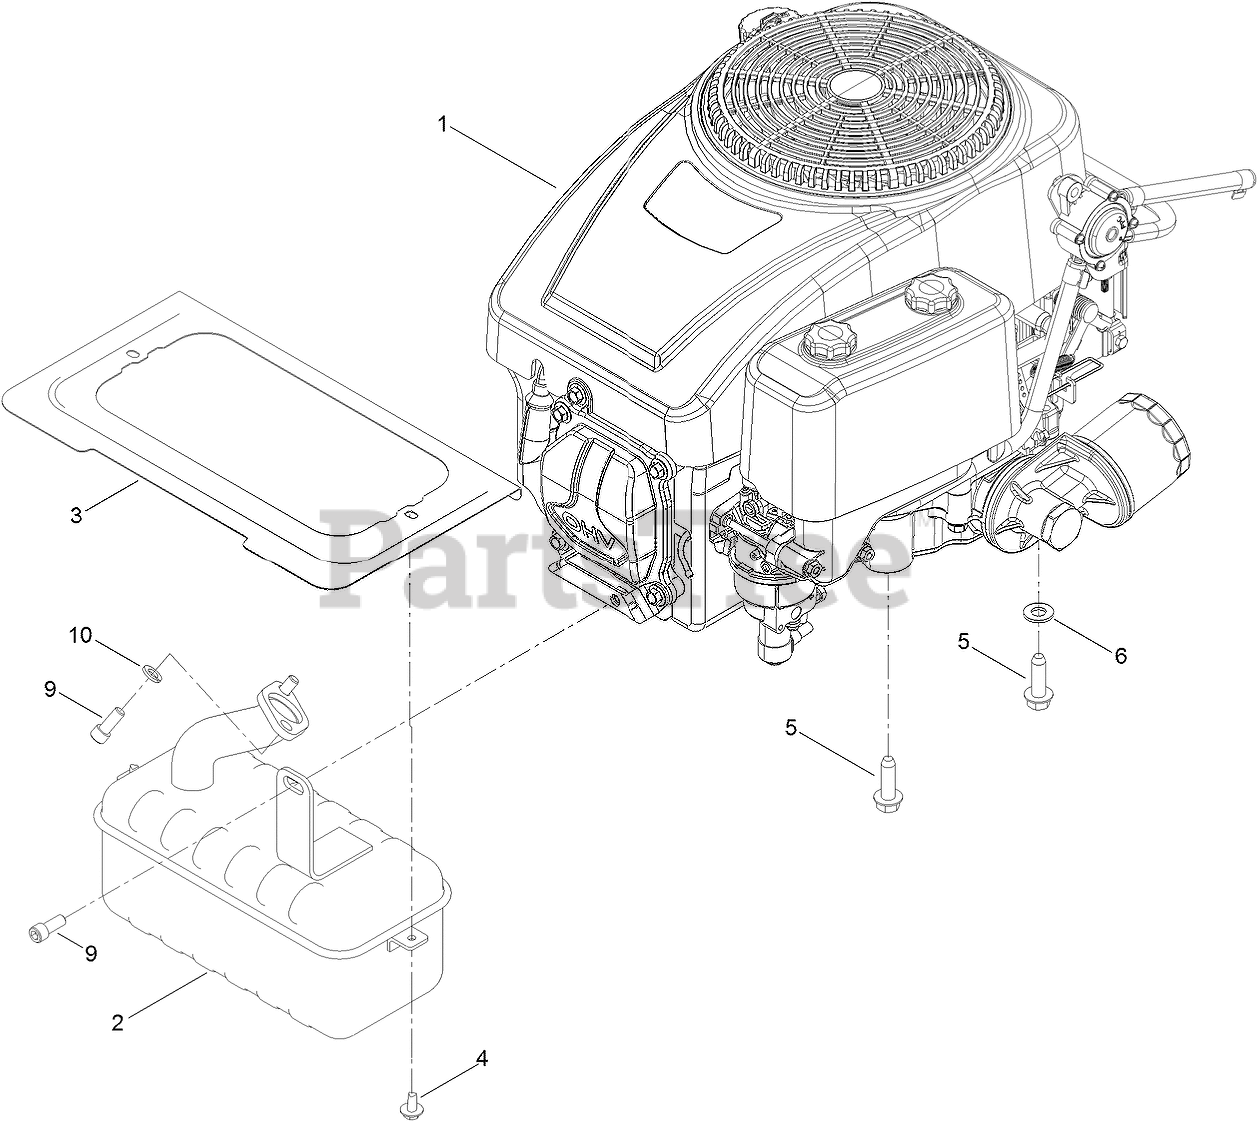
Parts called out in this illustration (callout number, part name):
1	ENGINE-1P92F-1
2	MUFFLER
3	SHIELD-HEAT
4	SCREW-HHFTF
5	SCREW-TAPTITE
6	WASHER-FLAT
9	SCREW-HSH
10	WASHER-LOCK
